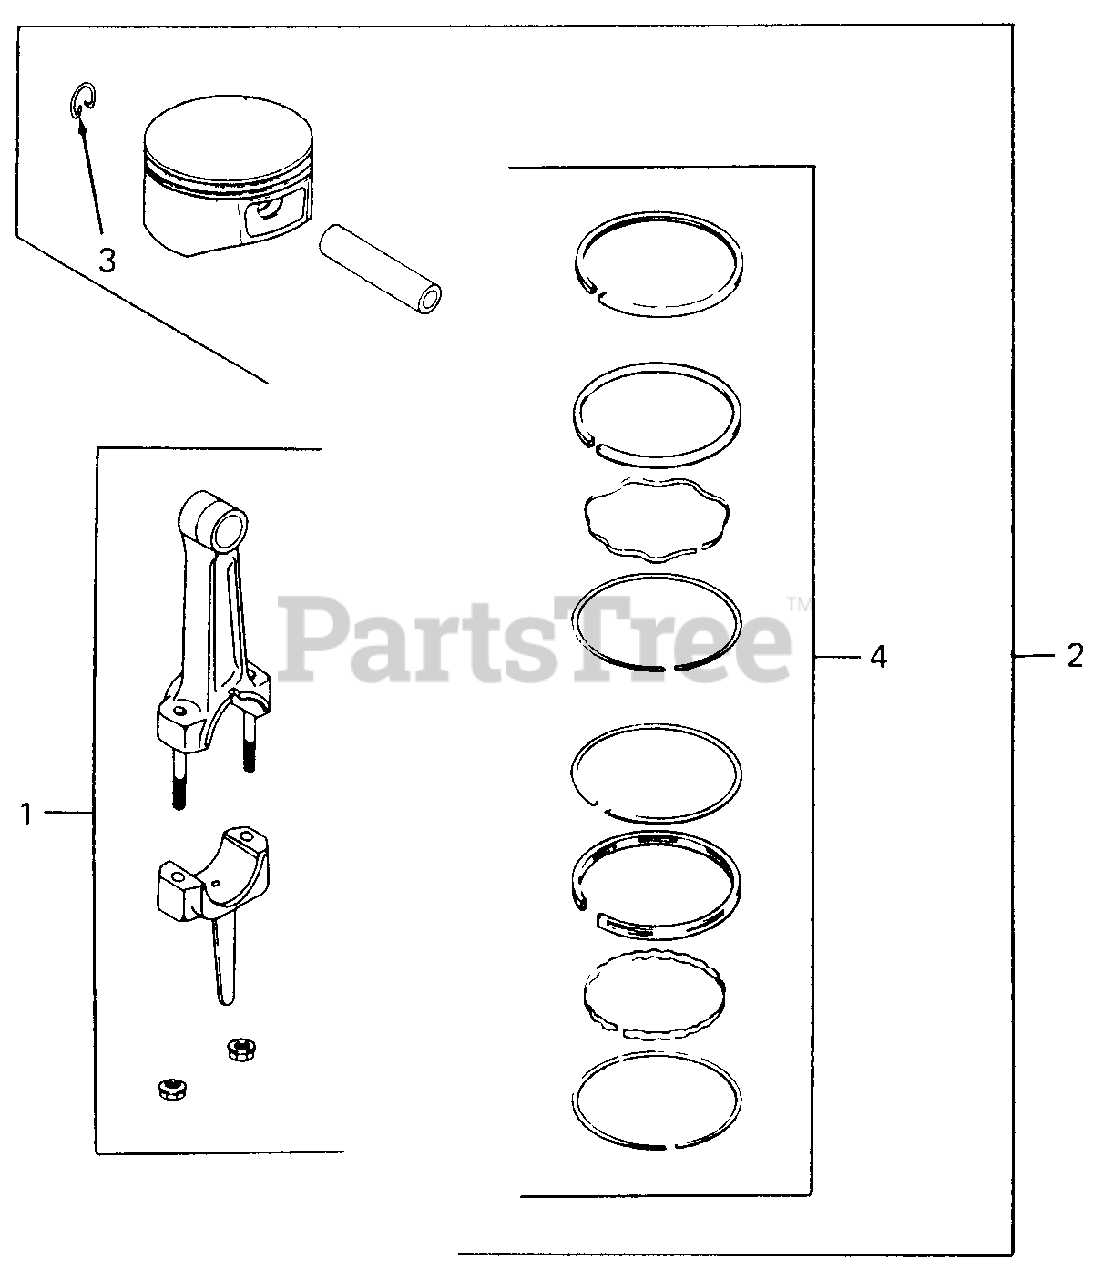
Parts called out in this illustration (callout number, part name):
1	Connecting Rod (Std)
2	Piston w/Ring Set (Std)
3	Retainer, Piston Pin
4	Ring Set (Std & .003)
